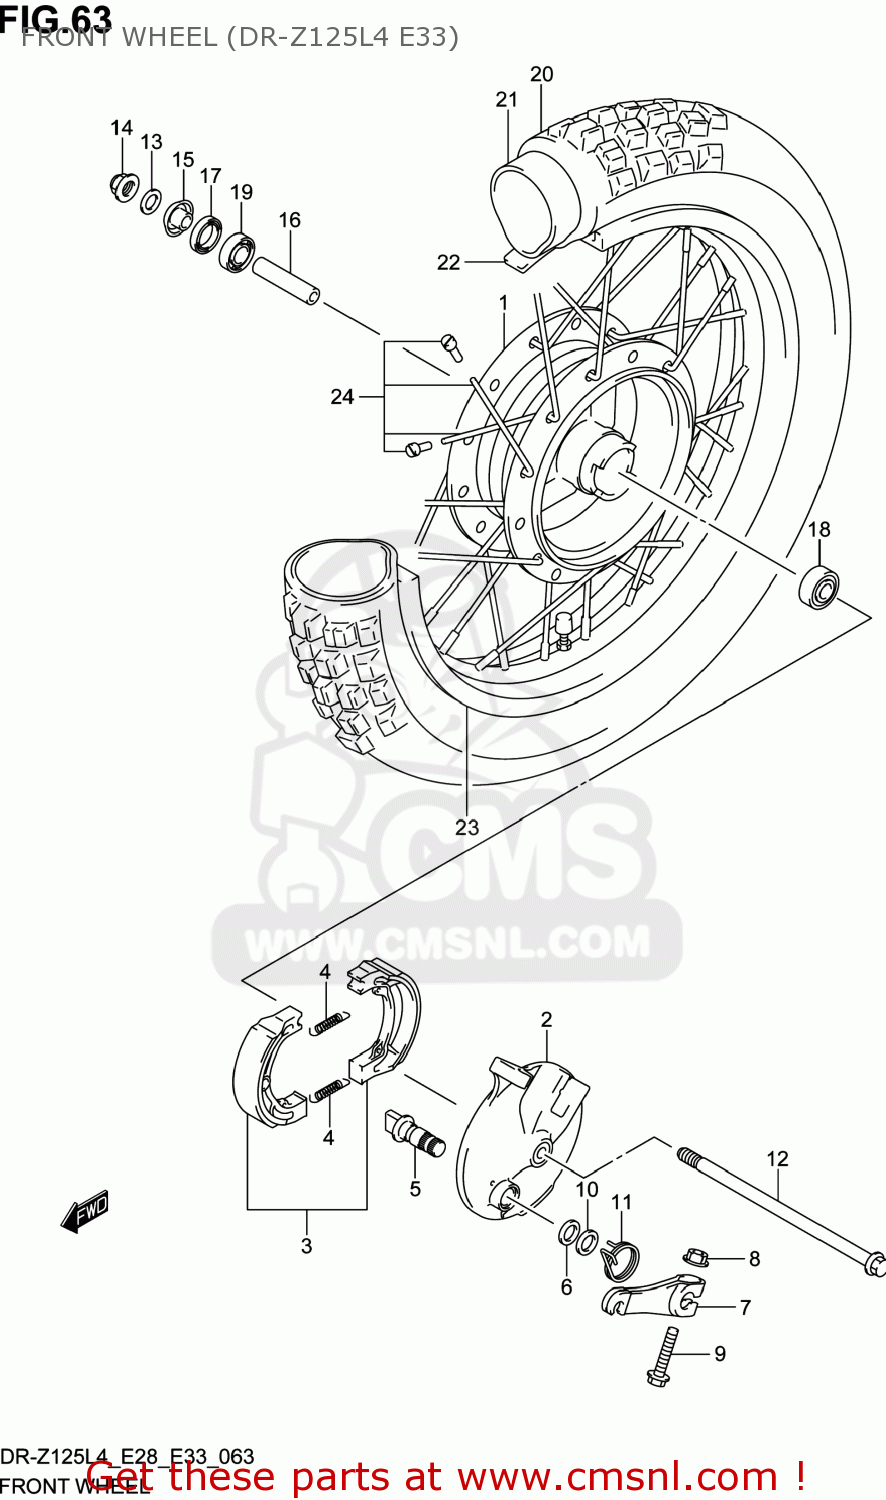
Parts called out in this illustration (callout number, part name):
1	HUB,FR WHEEL
2	PANEL,FR BRAKE ANCHOR
3	SHOE & SPRING SET,BRAKE (NAS)
4	SPRING
5	CAM,FR BRAKE
6	O RING(D:2.5,ID:13.8)
7	LEVER,FR BRAKE CAM
8	NUT
9	BOLT
10	WASHER(14.5X22X1.6)
11	SPRING,FR BK CAM LEVER RETURN
12	AXLE,FR
13	WASHER(10.5X20X3.2)
14	NUT
15	SPACER,FR AXLE,R
16	SPACER(10.1X16X51)
17	SEAL,OIL(15X31X5)
18	BEARING
19	BEARING
20	TIRE,FR
21	TUBE ASSY,WHEEL INNER
22	PROTECTOR,WHEEL INNER TUBE
23	RIM,FR WHEEL(17X1.40)
24	SPOKE SET,FR WHEEL
